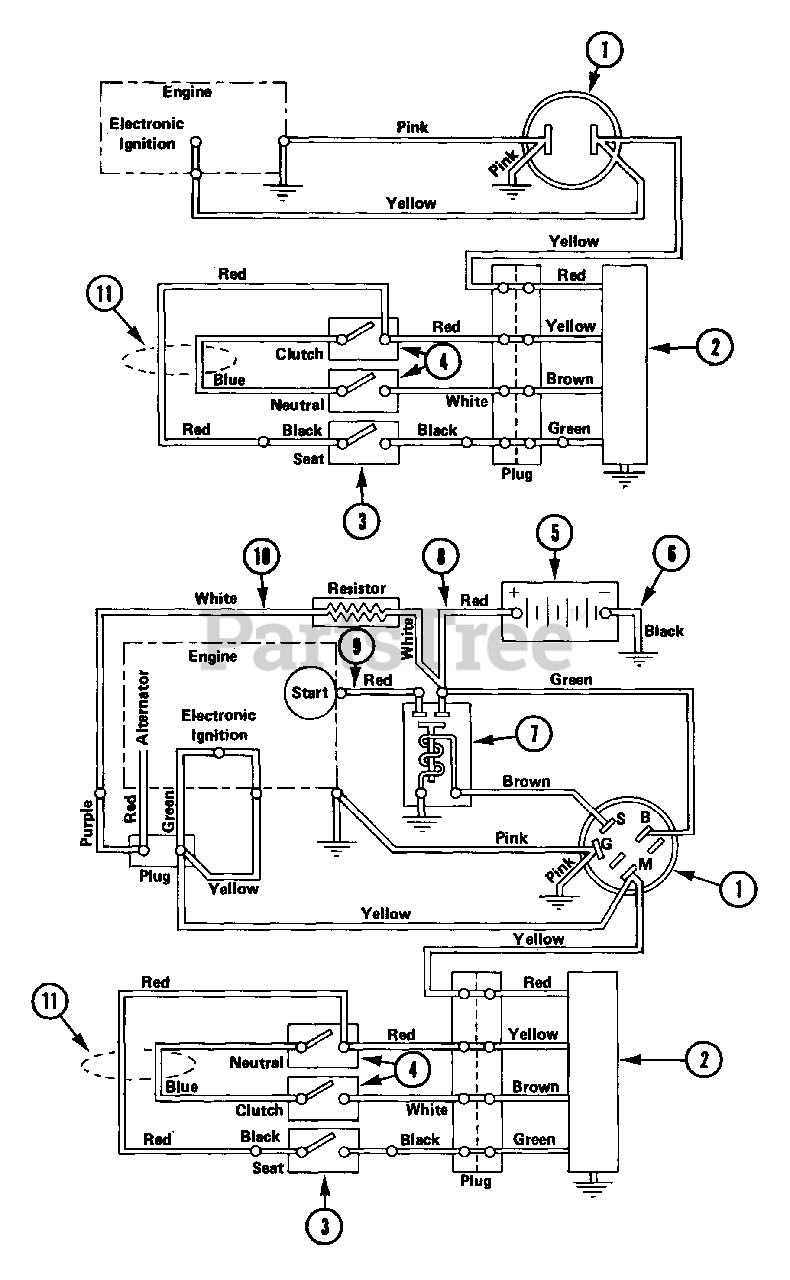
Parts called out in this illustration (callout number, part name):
1	KEY SWITCH ASSEMBLY
1	IGNITION SWITCH ASSEMBLY
1	KEY SWITCH
2	MODULE
3	SWITCH SEAT
4	SWITCH ASSEMBLY
4	SWITCH ASSEMBLY, N.O./N.O.
5	BATTERY
6	GROUND CABLE
7	SOLENOID
8	STARTER CABLE 6.75"
9	STARTER CABLE
10	CHARGING WIRE
11	WIRE HARNESS
12	REGULATOR
